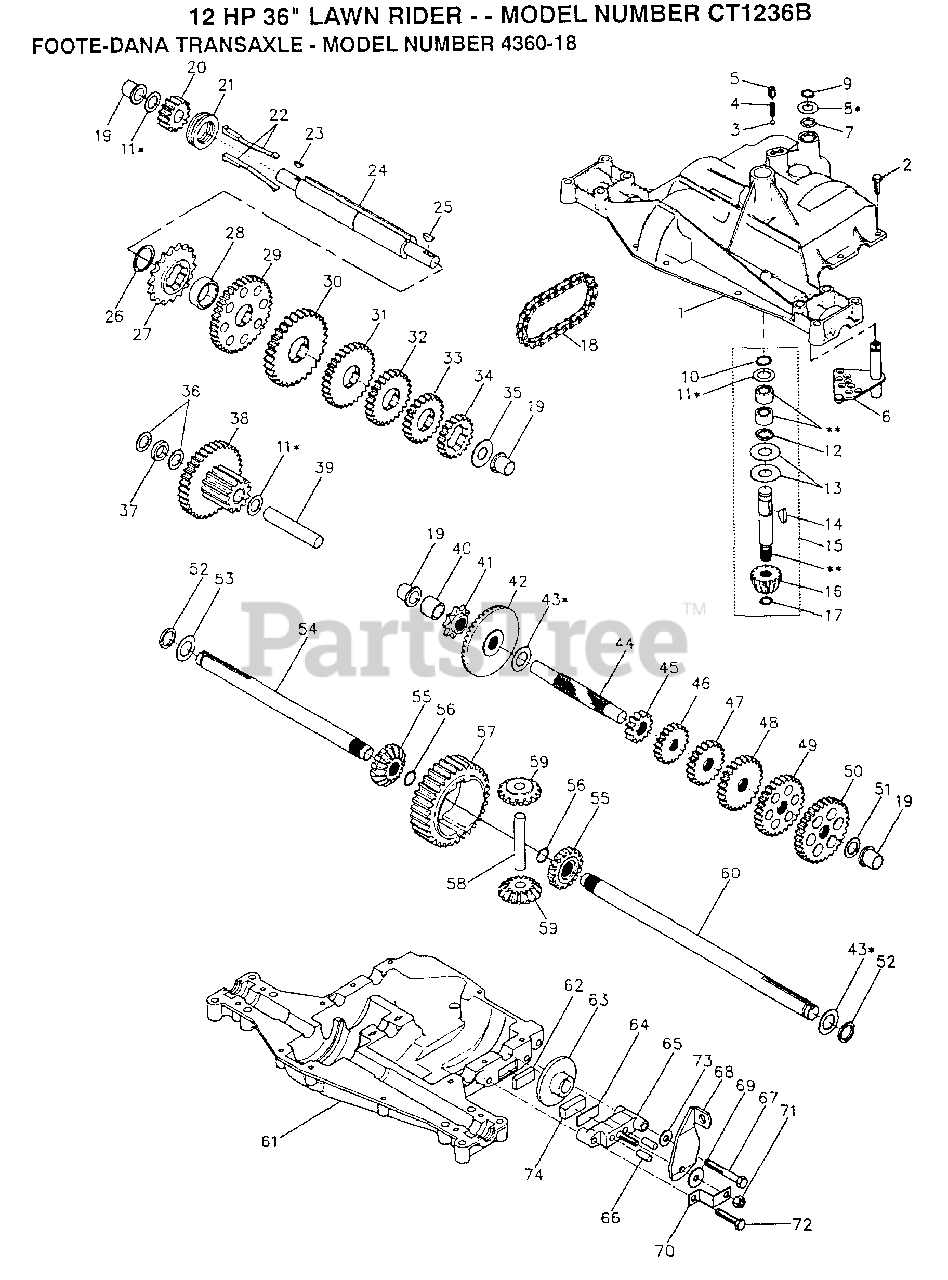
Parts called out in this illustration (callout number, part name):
3	"DETENT, BALL(68003)"
4	"SPRING, DETENT LT"
5	"SCREW, SET LT"
7	ORING T
9	RETAINING RING LT
10	RETAINING RING LT
11	WASHER
12	O-RING T
13	WASHER T
14	WOODRUFF KEY
15	IMPUT KIT T
16	PINION 14T T
17	"RING,RETAINING LT"
18	"CHAIN,24 PTCH LT"
19	BEARING.FLNG.5510
22	KEY T
25	WOODRUFF KEY
26	"RING,RETAINING LT"
27	SPROCKET 18T T
28	SPACER YT
29	KIT.GEAR.12/37TH
32	GEAR 25T LT
33	GEAR SPUR 22 TT
35	"WASHER, PLAIN LT"
36	WASHER 025
37	SPACER
38	ASSM GEAR COMB
39	SHAFT IDLER T
40	SPACER T
41	SPROCKET 9T LT
43	WASHER LT
44	SHAFT T
48	"GEAR, SPUR 25T LT"
49	GEAR 28T T
50	"GEAR, SPUR 31T LT"
51	WASHER 060
53	WASHER 062
55	GEAR 15T T
56	"RING,RETAINING LT"
58	SHAFT T
59	GEAR 1ST T
62	PUCK T
63	BRAKE DISC. T
64	SPACER LT
66	PIN T
67	SCREW T
68	LEVER ACTUATOR
69	WASHER LT
71	NUT.LOCK.5/16-24
72	"SCREW, TAPPING LT"
73	WASHER T
74	PUCK T
